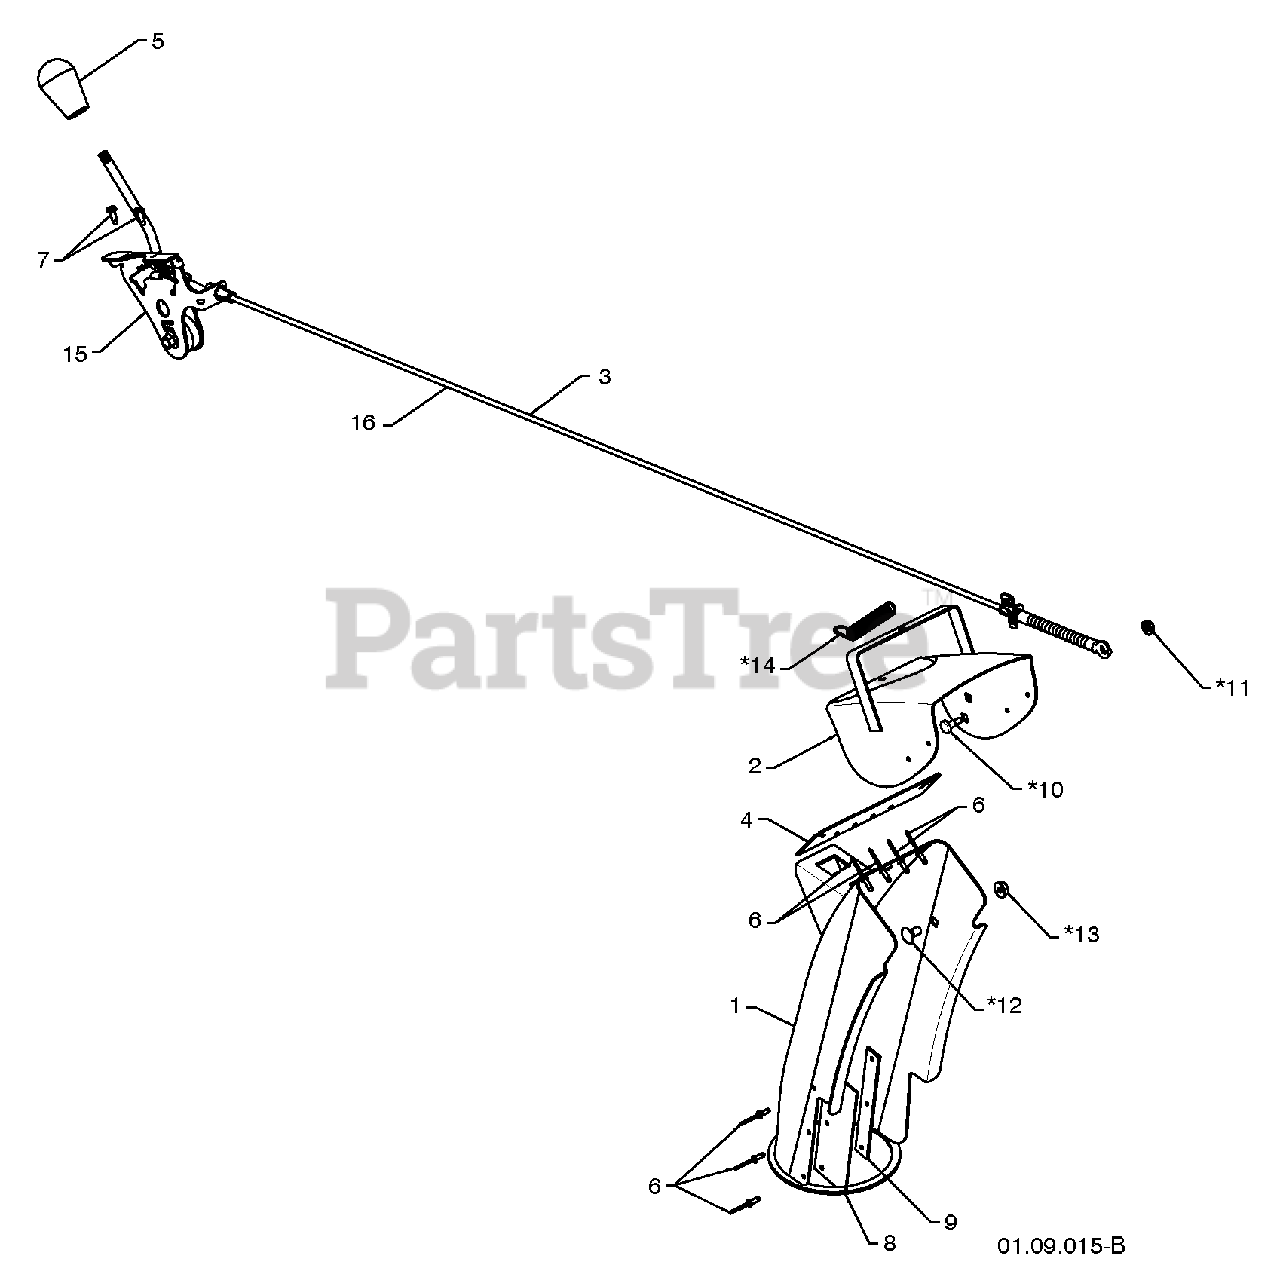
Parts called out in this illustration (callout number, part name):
1	CHUTE WELDMENT
2	DEFLECTOR WELDMENT
3	DEFLECTOR CONTROL ASSEMBLY
4	DEFLECTOR SEAL
5	KNOB BLACK
6	POP RIVET
7	SCREW 10-24 X .625
8	CHUTE SNOW SHIELD
9	SHIELD RETAINER STRAP
10	SHOULDER BOLT 1/4-20 X .375
11	NUT 1/4-20
12	CARRIAGE BOLT 3/8-16 X .625
13	NUT 5/16-18
14	DEFLECTOR SPRING
15	DEFLECTOR CONTROL
16	DEFLECTOR CABLE BLACK
